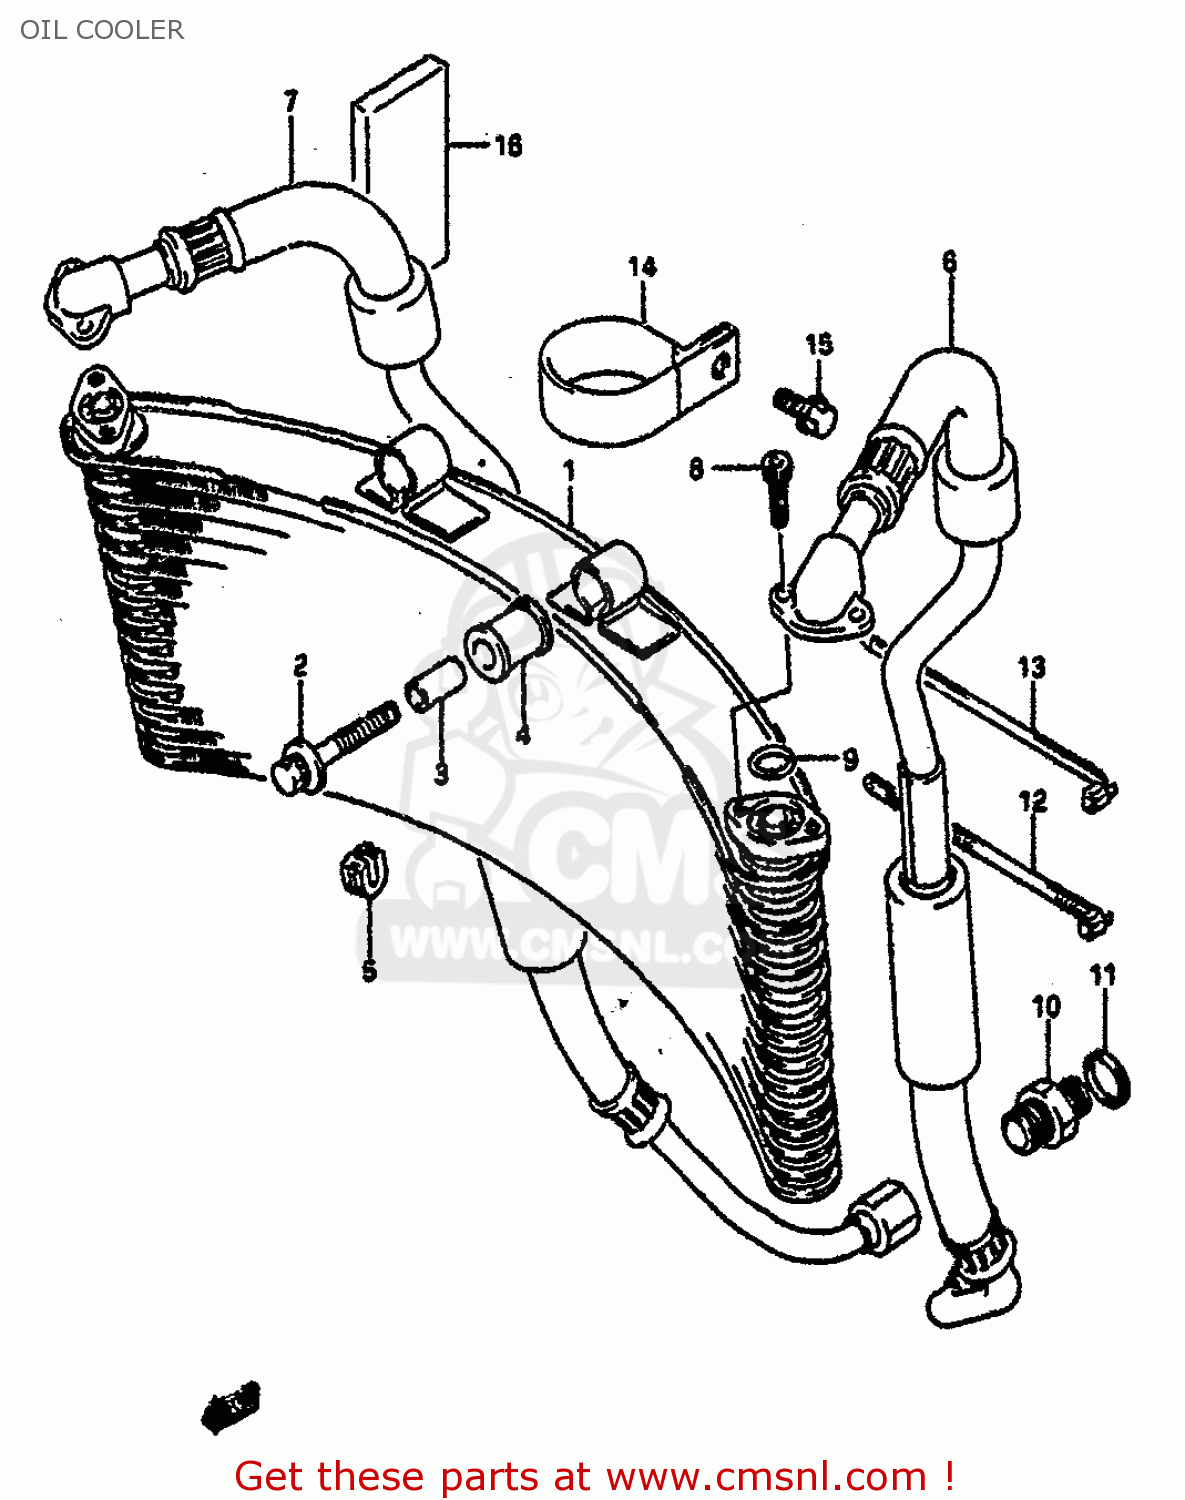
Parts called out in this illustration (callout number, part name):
1	COOLER ASSY,OIL
2	BOLT(8X40)
3	SPACER (8.8X12X24.5)
4	CUSHION,OIL COOLER NO.1
5	CUSHION,OIL COOLER NO.2
6	HOSE,OIL COOLER,L
7	HOSE,OIL COOLER,R
8	BOLT
9	O RING(D:2.4,ID:12.3)
10	BOLT UNION
11	GASKET(16X22X2) (NAS)
12	CLAMP
13	CLAMP(L:235)
14	CLAMP
15	BOLT
16	PROTECTOR
